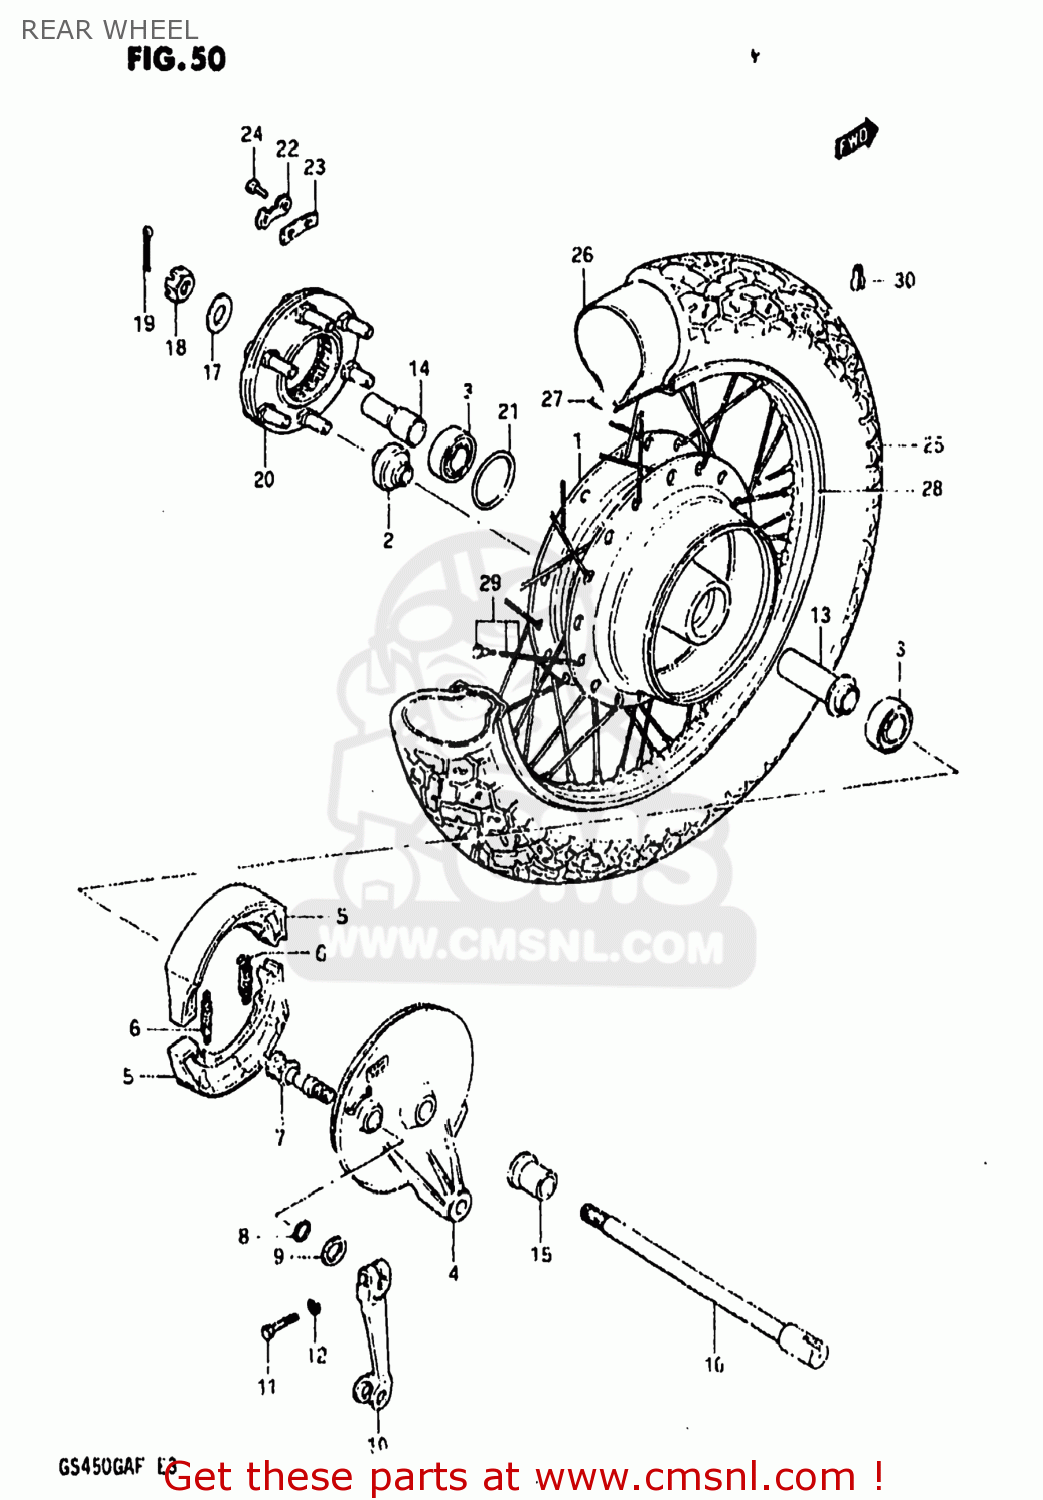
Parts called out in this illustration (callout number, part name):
1	HUB,REAR
2	CUSHION,REAR DRUM
3	BEARING
4	PANEL,REAR HUB
5	SHOE,BRAKE
6	SPRING,BRAKE SHOE
7	CAM,FRONT BRAKE
8	O-RING,BOSS
9	WASHER (15X24X1.6)
10	LEVER,RR BRAKE CAM
11	BOLT
12	LOCK WASHER
13	SPACER,REAR HUB BEARING
14	SPACER,REAR AXLE,LEFT
15	SPACER,REAR AXLE,RIGHT
16	AXLE,REAR
17	WASHER(16.5X36X3.2)
18	NUT
19	PIN,COTTER
20	JOINT ASSEMBLY,REAR HUB DRUM
21	O RING(D:2.1,ID:65)
22	WASHER
23	WASHER,THRUST(T:1.6)
24	BOLT(6X16)
25	TIRE
26	TUBE ASSY,WHEEL,INNER 4.60-16
27	PROTECTOR,WHL INR TUBE
28	RIM,FRONT WHEEL (2.15X16)
29	SPOKE SET,REAR WHEEL
30	BALANCER,WHEEL (B)
